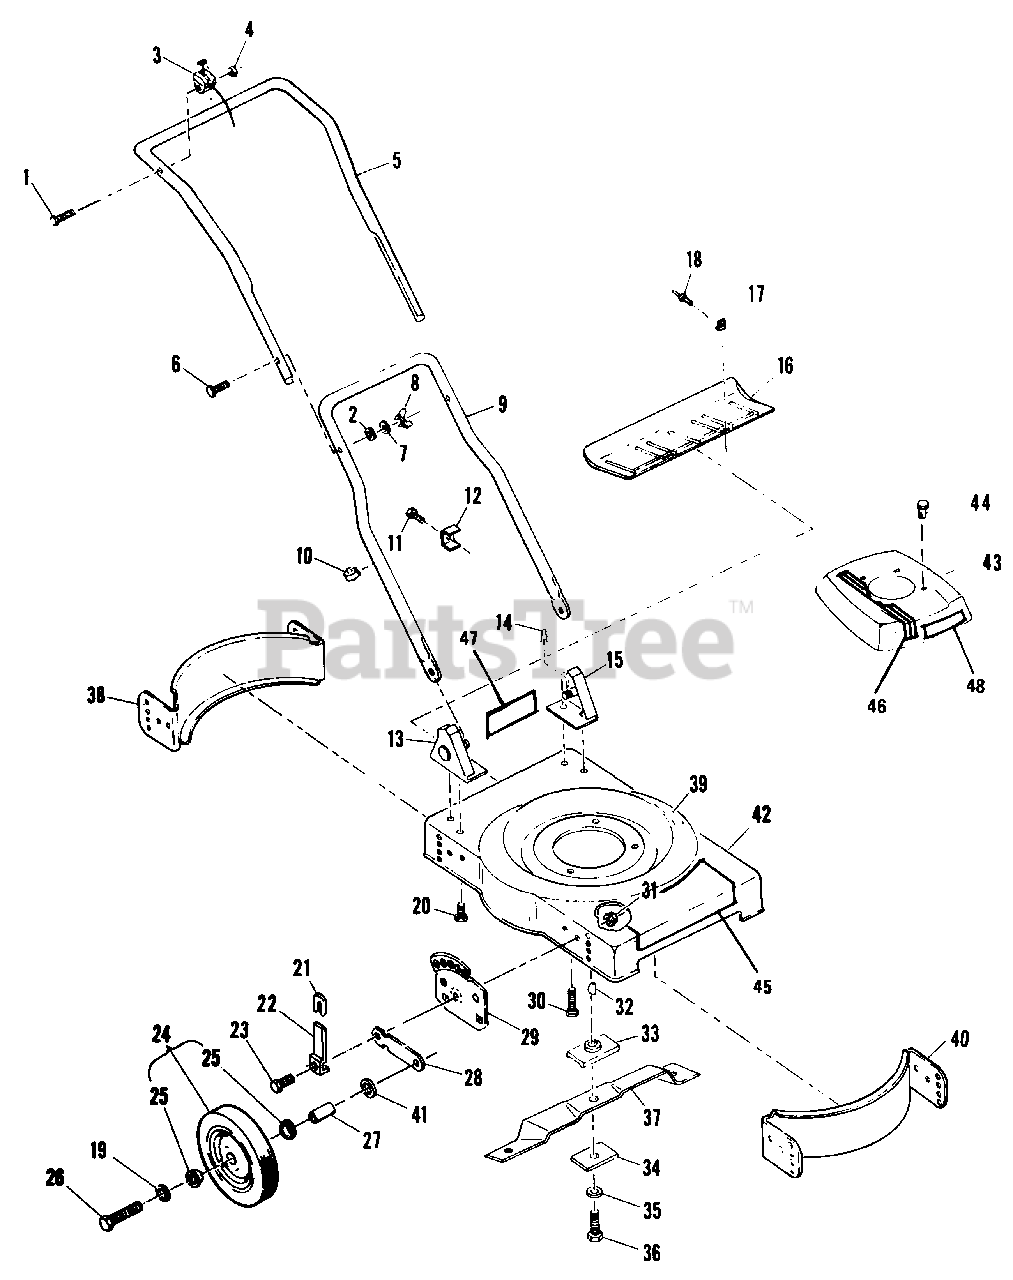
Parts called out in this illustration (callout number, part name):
1	BOLT, Throttle
2	WASHER, Curved
3	CONTROL, Throttle
4	NUT, Throttle
5	HANDLE, Folding
6	BOLT, Handle
8	NUT, Wing
10	CLAMP, Throttle
11	SCREW, Casing
12	CLAMP, Casing
13	BRACKET ASSY, RH
14	CLIP, Hairpin
15	BRACKET ASSY, LH
16	TRAILGUARD
18	RIVET, Pop
19	WASHER, 3/8
20	BOLT, 1/4-20 x 5/8
23	BOLT, Shoulder,
24	WHEEL ASSY, W/Bearing 8"
25	BEARING, Wheel
26	BOLT, Axle
27	SPACER, Wheel
29	PLATE, Wheel Adj.
30	SCREW, Engine
31	NUT, Baffle
32	KEY, Engine Shaft
33	ADAPTER ASSY, Blade
34	SPACER, Blade Adapter
35	WASHER, Blade
36	BOLT, Blade
38	BAFFLE, Rear
39	DECAL, Instructional
40	BAFFLE, Front
41	WASHER, Cupped
44	SCREW, Shroud
45	DECAL, Deck, Simplicity
46	DECAL, Stripe
47	DECAL, Simplicity 6"
48	DECAL, Mulcher 21"
